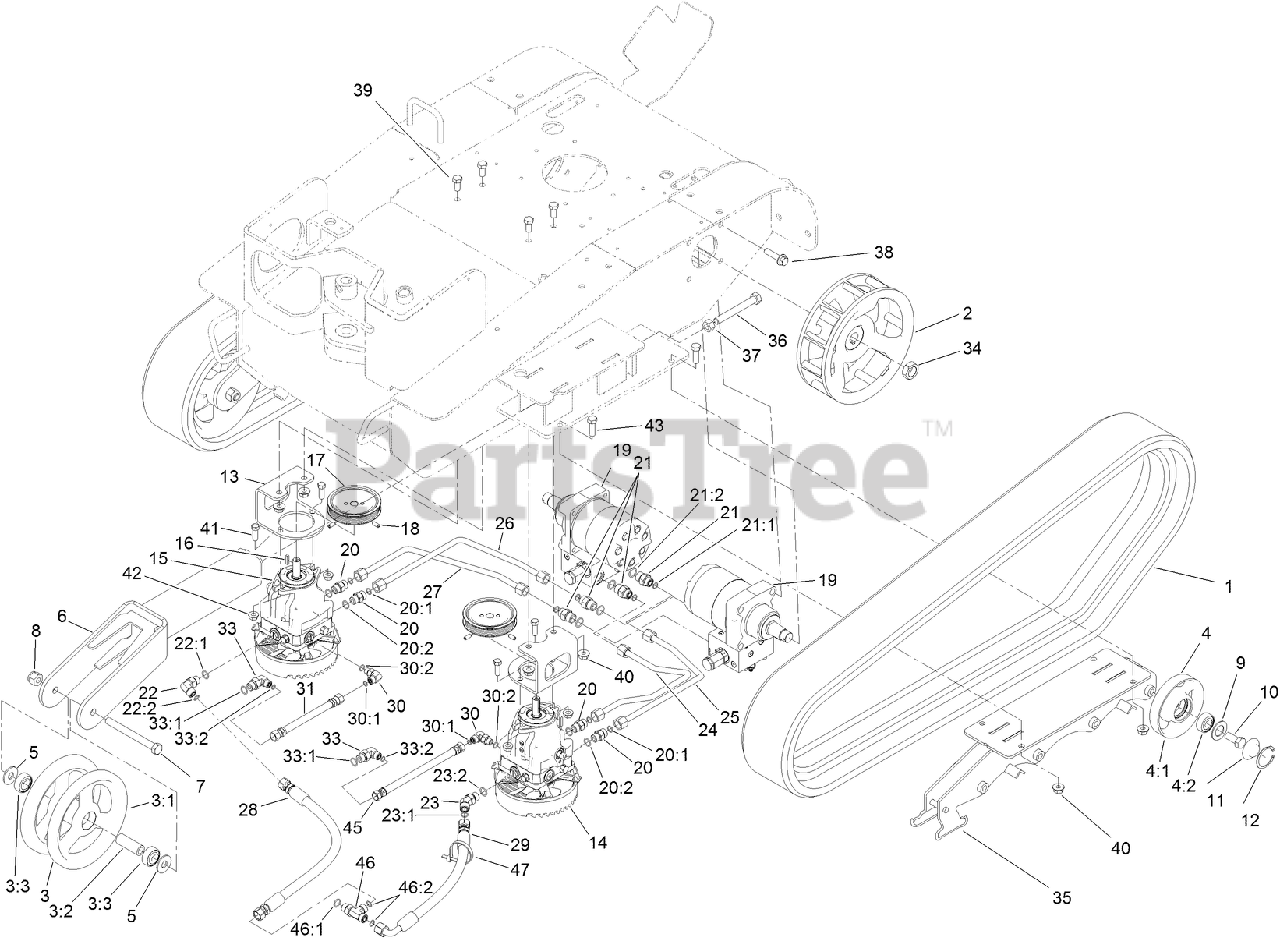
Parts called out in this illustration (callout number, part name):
1	TRACK-RUBBER
2	WHEEL-DRIVE
3	TENSIONER WHEEL ASM
3:1	WHEEL-TENSIONER
3:2	SPACER-WHEEL, TENSIONER
3:3	BEARING-BALL
4	WHEEL-TENSIONER
4:1	WHEEL-TRACK
4:2	BEARING-BALL
5	WASHER-FLAT
6	ARM-TENSIONER
7	SCREW-HH
8	NUT-HEX
9	Gasket-Bogie
10	SCREW-HH
11	CAP-WHEEL, BEARING
12	RING-SNAP, INTERNAL
13	BRACKET-MOUNT, PUMP
14	PUMP-HYD, LH
15	PUMP-HYD, RH
16	KEY-PUMP
17	Sheave
18	SCREW-SET, HSH
19	HYD MOTOR ASM
20	FITTING-STRAIGHT
20:1	O-RING
20:2	O-RING
21	FITTING-STRAIGHT
21:1	O-RING
21:2	O-RING
22	FITTING-ELBOW-90 DEG
22:1	O-RING
22:2	O-RING
23	FITTING-HYD, 45 DEG
23:1	O-RING
23:2	O-RING
24	TUBE-HYD
25	TUBE-HYD
26	TUBE-HYD
27	TUBE-HYD
28	HOSE-HYD
29	HOSE-HYD
30	FITTING-ELBOW, 90 DEG
30:1	O-RING
30:2	O-RING
31	HOSE-HYD
33	FITTING-HYD, 90 DEG
33:1	O-RING
33:2	O-RING
34	NUT-LOCK
35	MOUNT-WHEEL
36	SCREW-HH, TAP
37	NUT-HEX
38	SCREW-HHF
39	SCREW-HH
40	NUT-HHF
41	SCREW-HH
42	NUT-HF
43	SCREW-HH
45	HOSE-HYD
46	FITTING-TEE
46:1	O-RING
46:2	O-RING
47	TIE-CABLE
